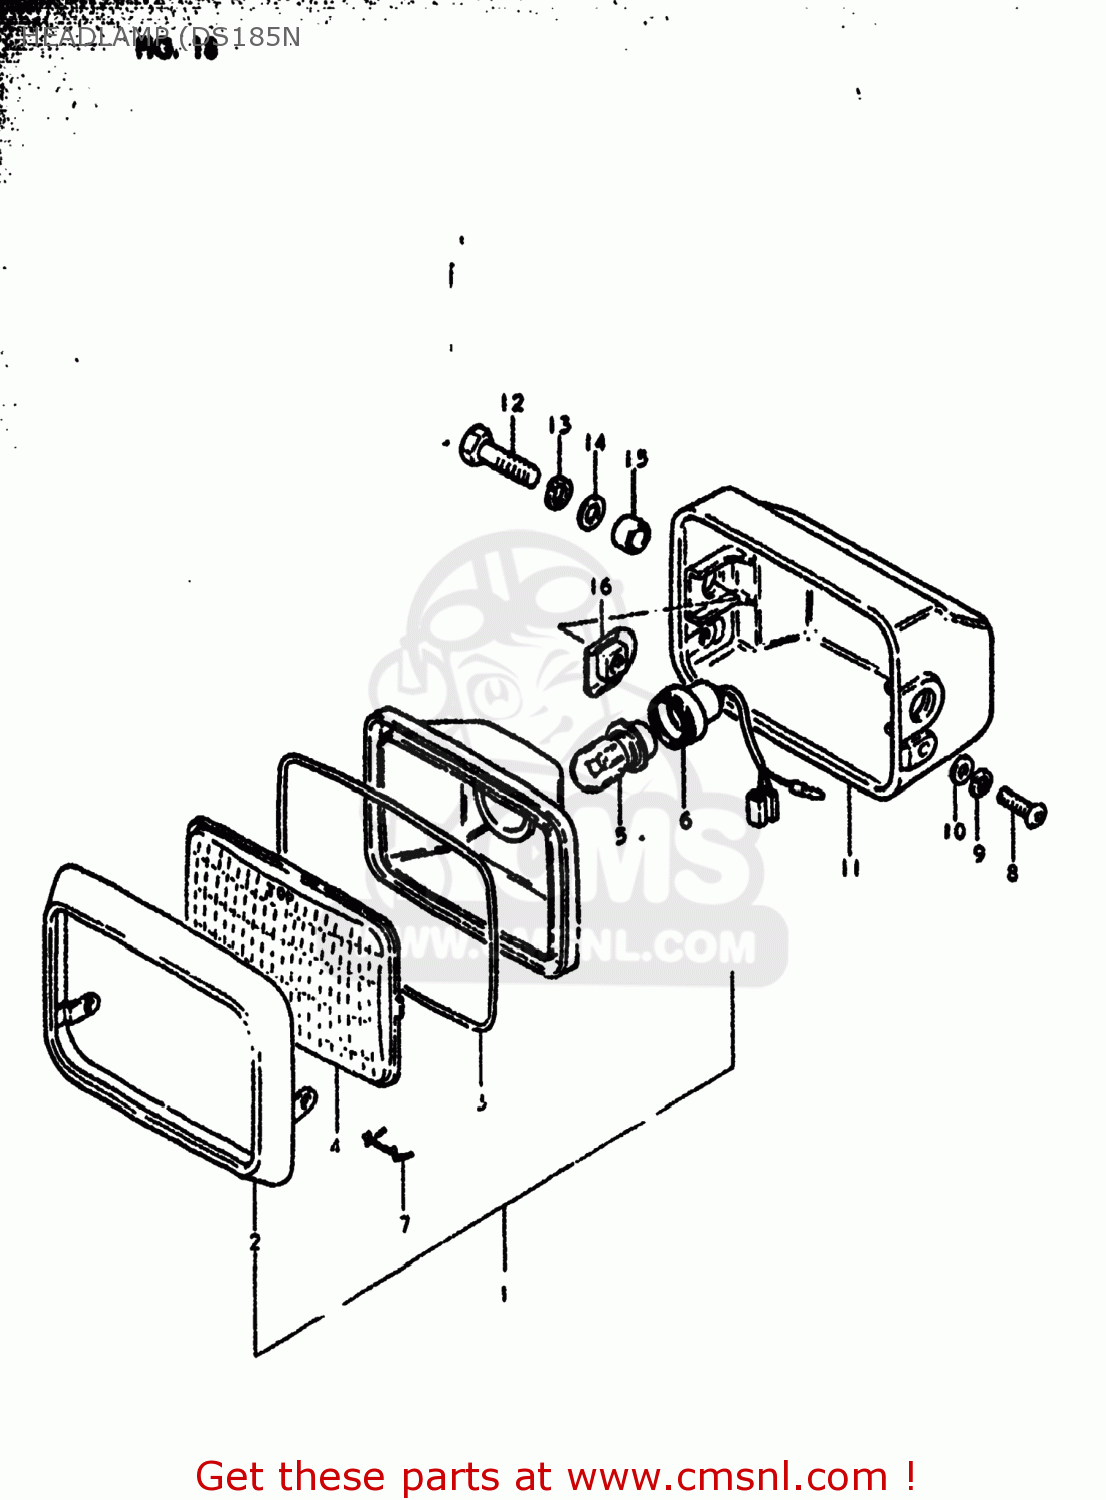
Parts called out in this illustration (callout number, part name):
1	LAMP ASSEMBLY,HEAD
2	RIM,HEADLAMP
3	GASKET,HEADLAMP LENS (NAS)
4	LENS,HEADLAMP (PLASTIC)
5	BULB(6V15/15W/STANLEY,A3598HA)
6	SOCKET,BULB
7	SPRING,HEADLAMP UNIT
8	SCREW
9	LOCK WASHER
10	WASHER
11	HOUSING,HEADLAMP
12	BOLT
13	LOCK WASHER
14	WASHER
15	SPACER (8.8X12X7)
16	PLATE,HEADLAMP HOUSING
